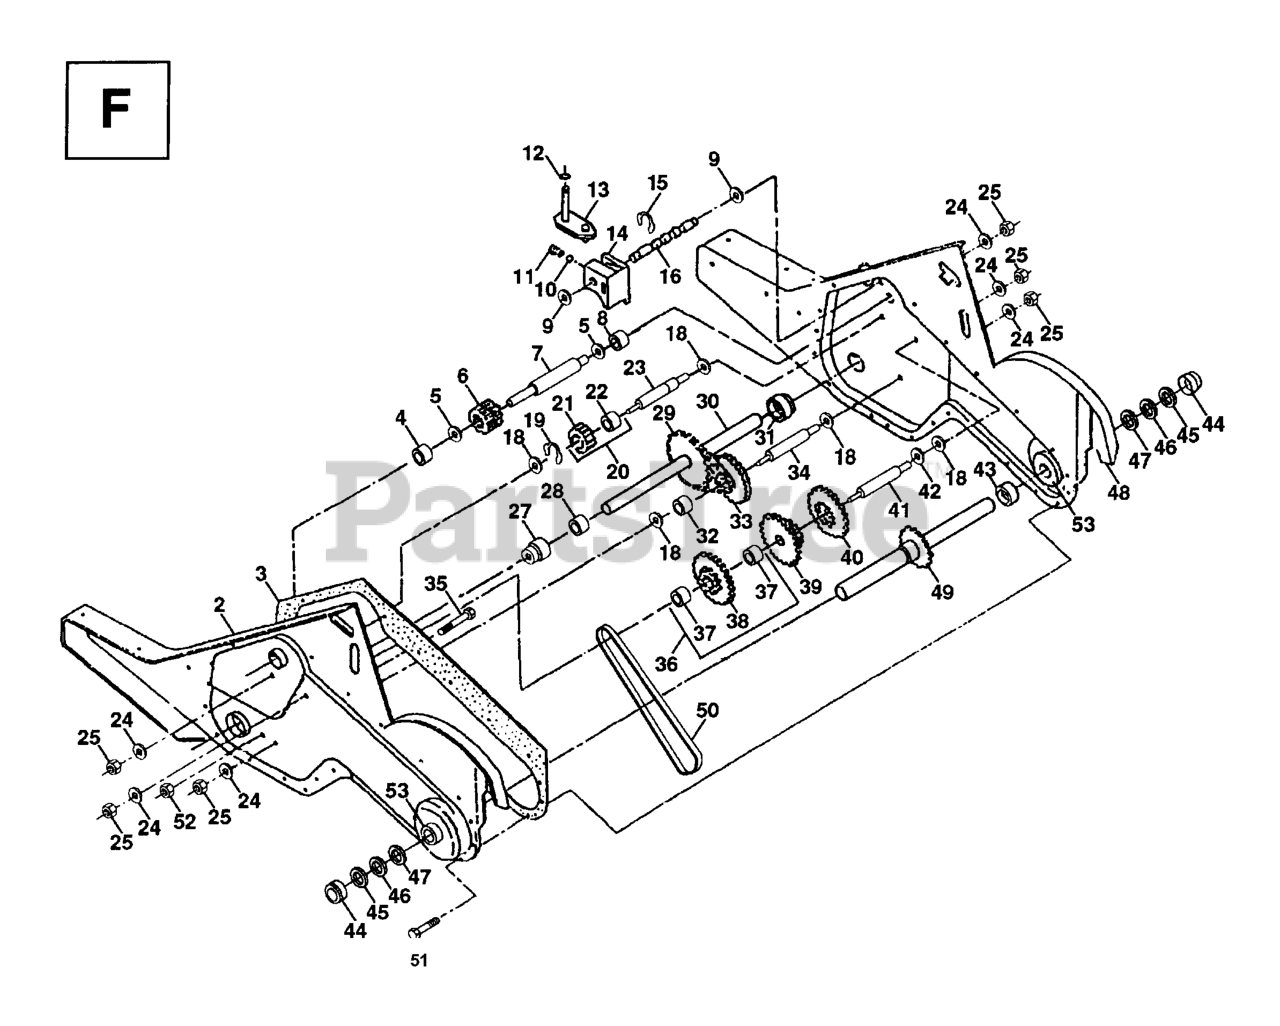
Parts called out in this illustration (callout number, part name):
1	TRANSMISSION ASSY
2	GEARCASE L.H.
3	GASKET TI
4	NEEDLE BRNG LT
5	THRUST WASHER
6	GEAR.PINION.INPUT
7	SHAFT-INPUT CRT
8	BEARING TI
9	WASHER SEAL CRT
10	STEEL BALL KIT
11	SPRING-SHIFT CRT
13	BRACKET ASM.SHIFT.CRT
14	SHIFT FORK TI
16	SHIFT SHAFT
20	GEAR ASSY CRT
21	GEAR-REV IDLR CRT
22	NEEDLE BEARING TI
24	LOCKWASHER
25	NUT.ASF.HEX.7/16
27	BEARING, SHAFT LH CRT
30	SHAFT ASSY
31	BEARING, SHAFT RH CRT
33	SPRCKT 8 GEAR CRT
34	SHAFT.SECONDARY.REDUCTION.CRT
35	SCRW WHIZ LOK CRT
36	SPROCKET ASSY W/ BRG
37	BEARING
38	SPROCKET TINE
41	SHAFT.REDUCTION.TILLER
42	BRNG RACE T
44	CUP
45	RING.SPIRAL.CRT.TILLER
47	OIL SEAL STD
48	GEARCASE R.H.
49	TINE SHAFT
50	CHAIN.TILLER
51	SCREW CRT
53	BEARING KIT
